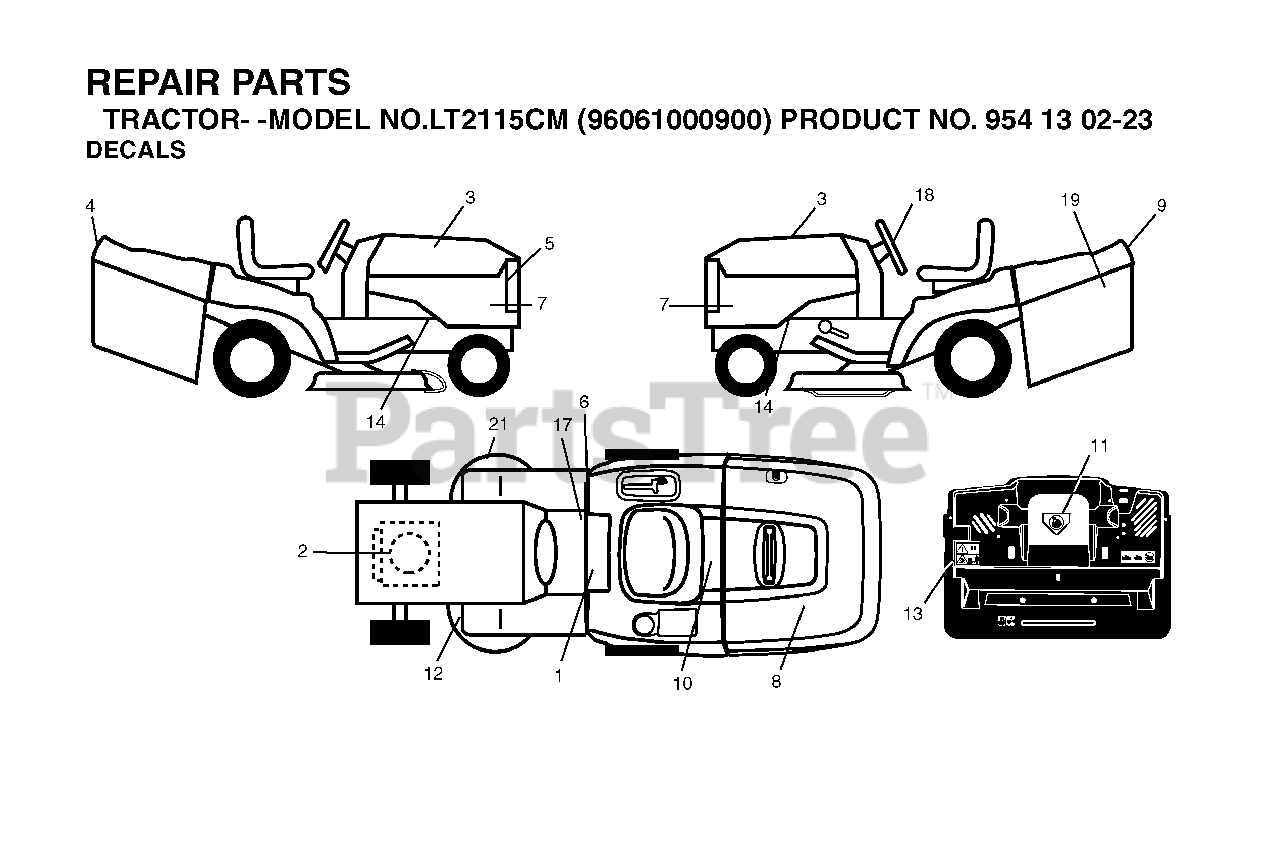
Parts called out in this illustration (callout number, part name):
1	DECAL READ OWNER'S MAN SYMS
4	DECAL.FENDER.LT2115CM
10	DECAL BTRY SYMBOLS
11	DECAL.INTERNATIONL.CUTFINGER
17	DECAL PARK BRAKE
